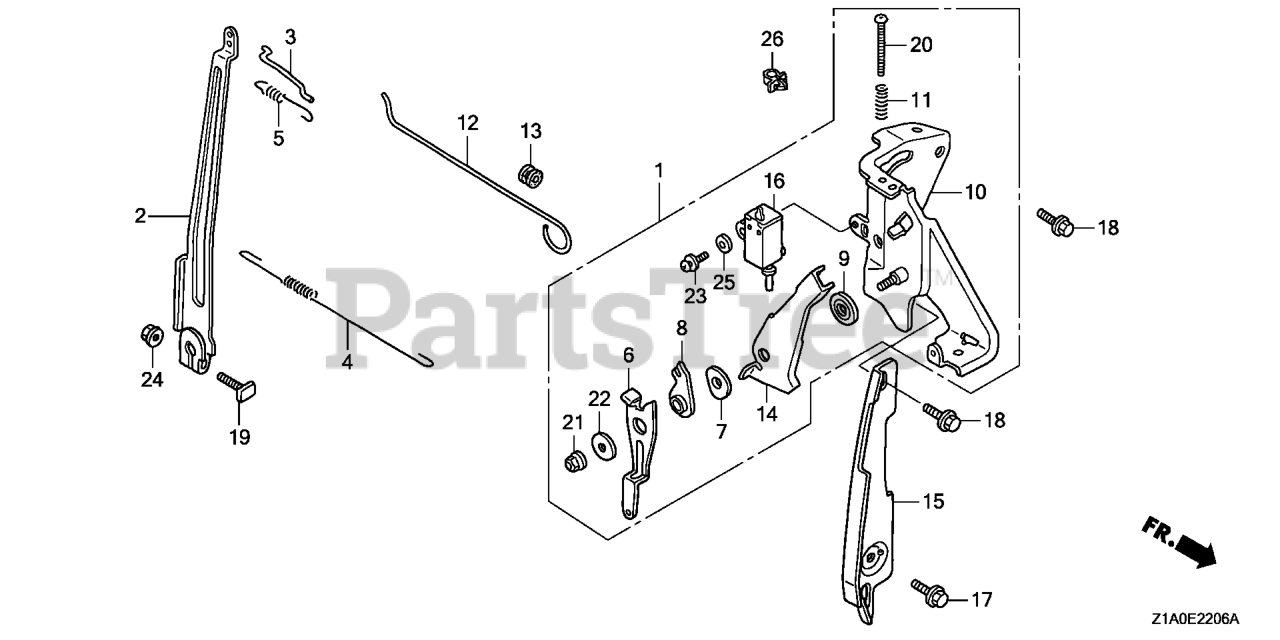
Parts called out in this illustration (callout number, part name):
1	CONTROL ASSY.
2	ARM, GOVERNOR
3	ROD, GOVERNOR
4	SPRING, GOVERNOR
5	SPRING, THROTTLE RETURN
6	LEVER, CONTROL
7	SPRING, LEVER
8	WASHER, CONTROL LEVER
9	SPACER, CONTROL LEVER
10	BASE, CONTROL
11	SPRING, CONTROL ADJUSTING Use from Engine SN 2327377.
12	ROD, CHOKE CONTROL
13	GROMMET, CHOKE ROD
14	LEVER, STOP
15	PLATE, SIDE
16	SWITCH ASSY., ENGINE STOP (N.O)
17	BOLT, FLANGE (6X12) (CT200)
18	BOLT, FLANGE (6X14)
19	BOLT, GOVERNOR ARM
20	SCREW, ADJUST
21	NUT, SELF-LOCK (6MM)
22	WASHER, WHEEL (6MM)
23	SCREW-WASHER (4X12)
24	NUT, FLANGE (6MM)
25	WASHER, PLAIN (4MM)
